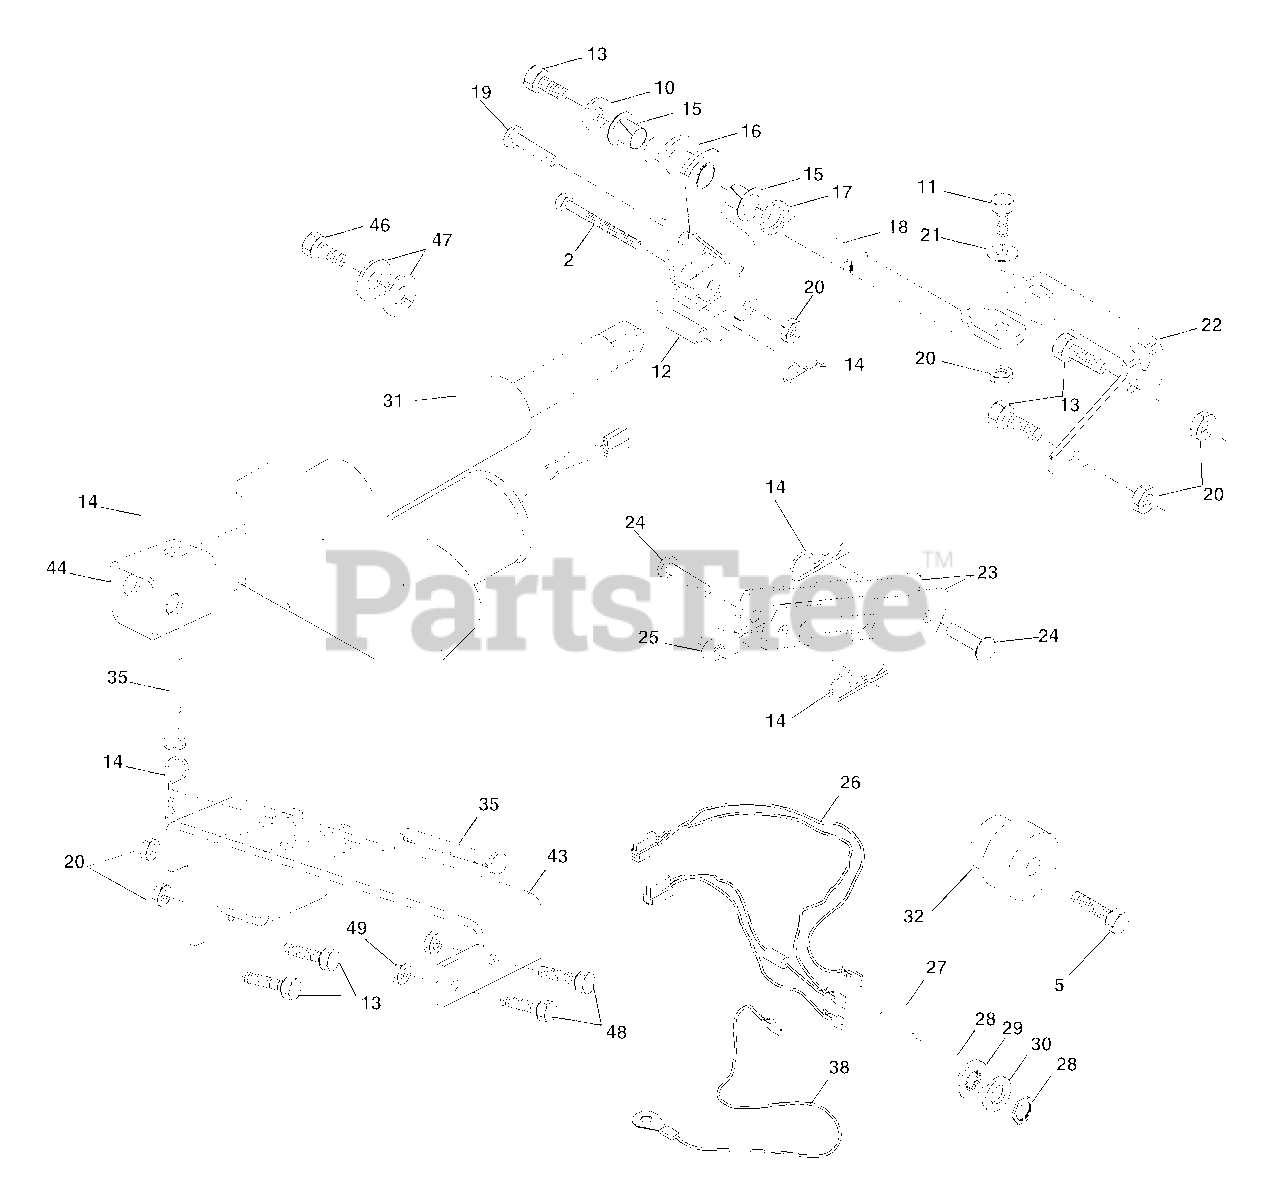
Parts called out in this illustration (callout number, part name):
2	Bolt, Hex 3/8-16 x 3-1/4 Grade 5
5	Bolt, Hex 3/8-16 x 1-3/8
10	Washer, Lock
11	Bolt, Hex 3/8-16 x 1-1/4
12	Bushing .384 x 1/2 x 1-1/4
13	Bolt, Hex 3/8-16 x 7/8
14	Spring, Retainer
15	Nyliner
17	Washer 21/32 x 1 x 21 Ga.
18	Rod, Pivot Support
19	Pin, Pivot 5/8 x 1-1/2
20	Locknut 3/8-16
21	Washer 13/32 x 7/8 x 16 Ga.
22	Bracket, Pivot Rod
23	Link, Lift
24	Pin, Pivot 1/2 x 3/4
25	Spacer
26	Harness, Lift Kit
27	Switch, Lift
28	Nut, Switch
29	Washer, Lock Int. Tooth
30	Washer 15/32 x 3/4 x 16 Ga.
31	Electric, Actuator
32	Hub, Lever Lift (Tapered)
35	Pin, Pivot 2-1/2"
38	Wire, Ground
43	Bracket, Frame
44	Tube, Pivot
46	Screw 5/16-18 x 1-1/4
47	Washer 11/32 x 1-1/2 x 10 Ga.
48	Bolt, Hex 5/16-18 x 1"
49	Locknut 5/16-18
